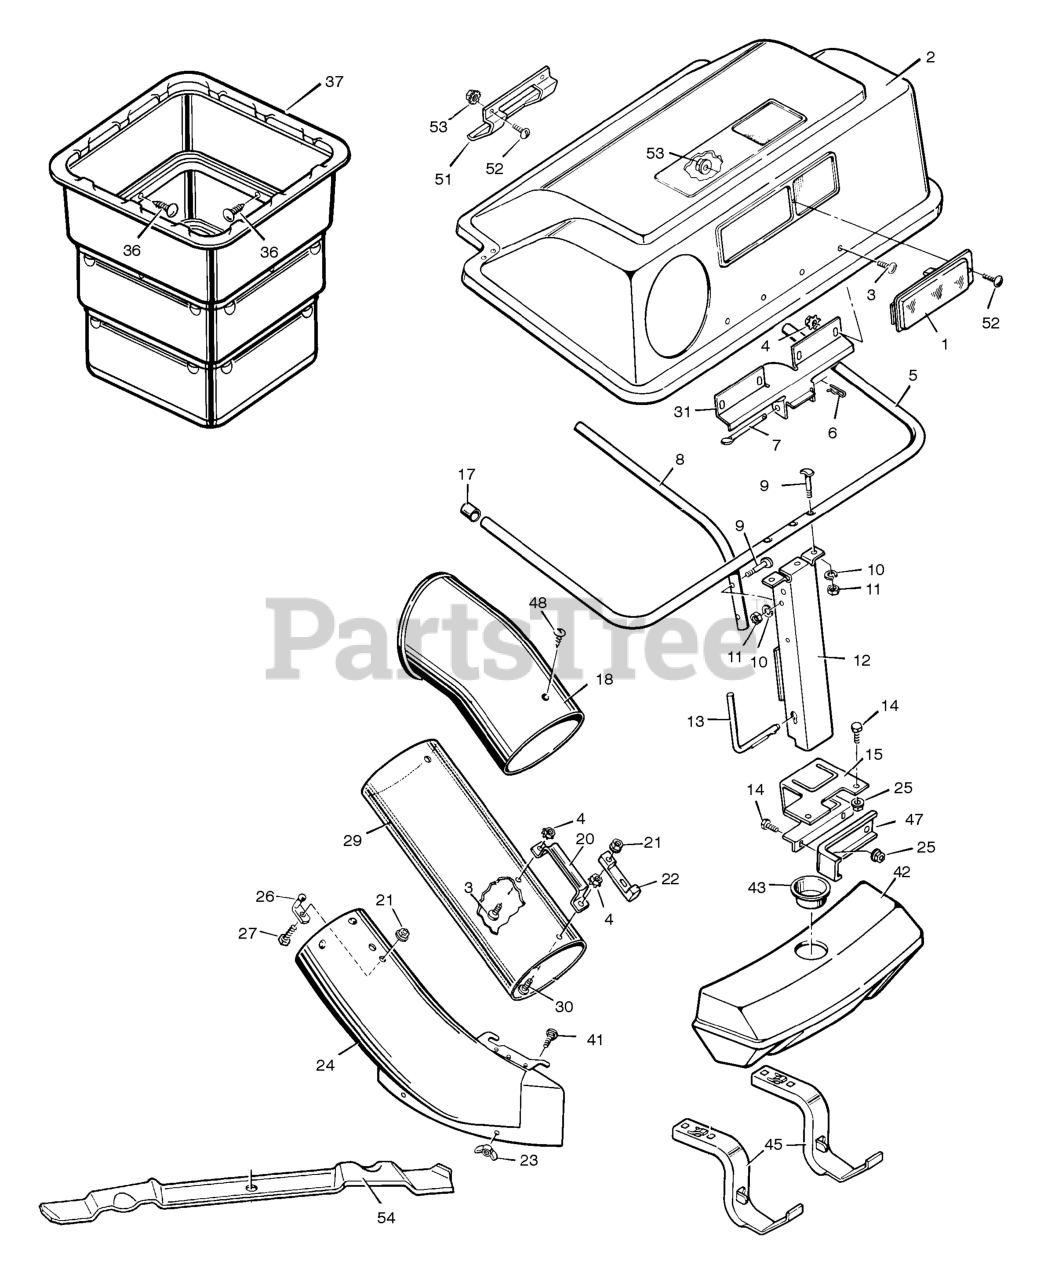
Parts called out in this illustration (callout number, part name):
4	Locknut
6	Pin, Hair
7	Pin, Hinge
8	Tube, Center
9	Bolt, Special
10	Lockwasher
11	Nut, Hex
12	Channel Assembly
13	Pin, Channel
14	Bolt, Hex
15	Hitch Assembly
17	Cap, End
20	HANDLE, Connect Tube
21	Locknut, Flange
22	Latch, Rubber
23	Wingnut
24	Tube, Chute Extension
25	Locknut
26	Pin, Latch
27	Bolt, Carriage
29	Tube, Connector
31	Hinge, Cover
36	Fastener, Plastic
37	Containers (Quantity 2)
41	Bolt, Carriage
42	Shell, Front Weight
43	Plug, Front Weight
45	Bracket, Front Weight
47	Bracket, Support
51	Handle, Plastic
53	Nut, Hex
54	Blade, High-Lift
